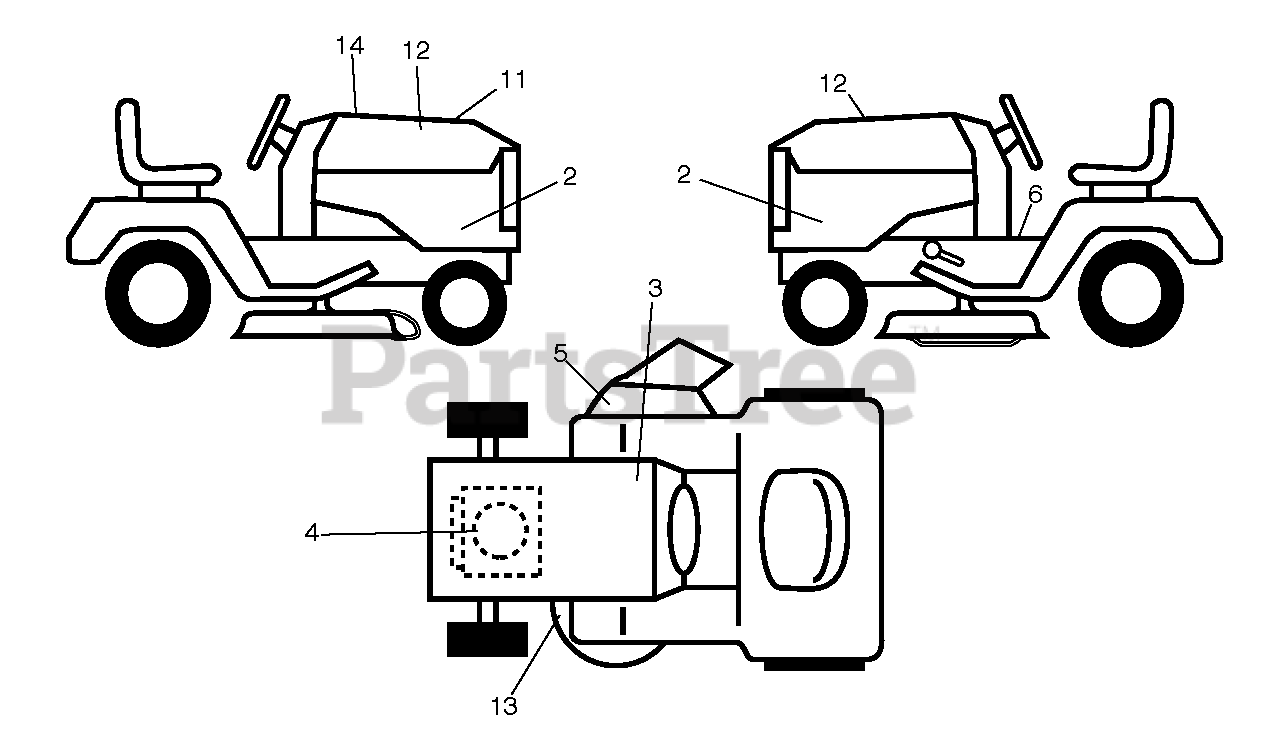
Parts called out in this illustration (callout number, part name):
2	DECAL.SIDE.PANEL.SRD17530
3	DECAL BTRY SYMBOLS
4	DECAL.ENG.BS.5HP.PB.278978
5	DECAL.WARN.DFLCTR/CTFRG.SRD
6	DECAL.FENDER.WARNING.ENGLISH
12	DECAL.BADGE.170MM.TEXTLOGO.
13	DECAL.V.BELT.30"
14	DECAL.WARNING.CUST.RESP.E85.
